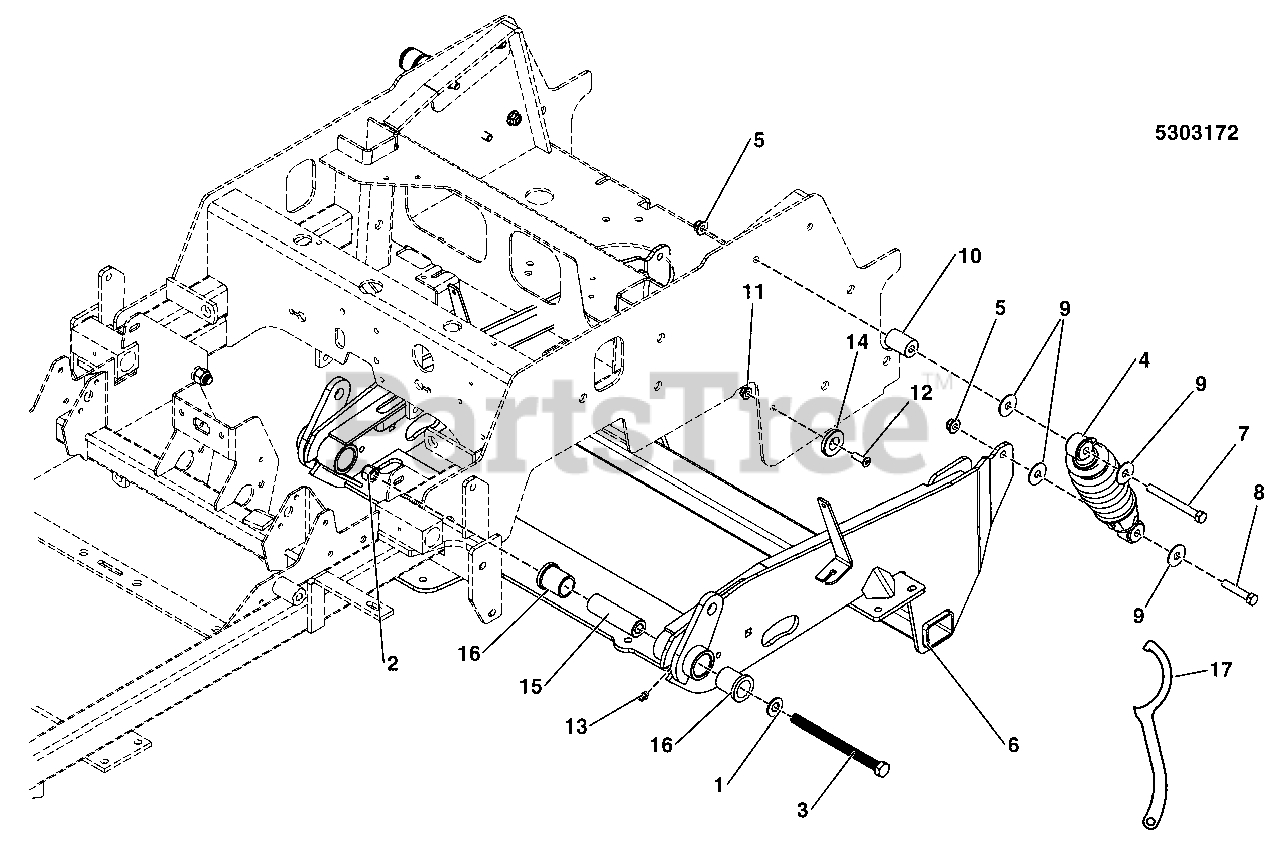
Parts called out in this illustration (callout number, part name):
1	WASHER, 1/2 SAE
2	NUT, 1/2-13 HEX NYLON LOCK
3	BOLT, 1/2-13 X 6-1/2" GD8 YZ
4	COIL - OVER SHOCK ASSEMBLY
5	NUT, 3/8 - 16 HEX NYLOCK FLANGE
6	CRADLE, Suspension
7	BOLT, 3/8-16 X 3-1/2" GD5 CZ
8	BOLT, 3/8-16 X 2, GD5, CZ
9	WASHER, 3/8" Fender
10	SPACER, .39 X 1.00 X 1.25, PM, CZ
11	NUT, 5/16-18 HEX NYLOCK FLANGE NUT
12	SCREW, 5/16-18 X 1, PHILLIPS HD, BZ
13	GREASE FITTING, 1/4-28 Straight
14	SPACER, .34 X 1.54 X .25 - UHMW
15	SPACER, .52 X 1.00 X 3.42
16	BUSHING, FLANGE
17	WRENCH, SPANNER, CZ
